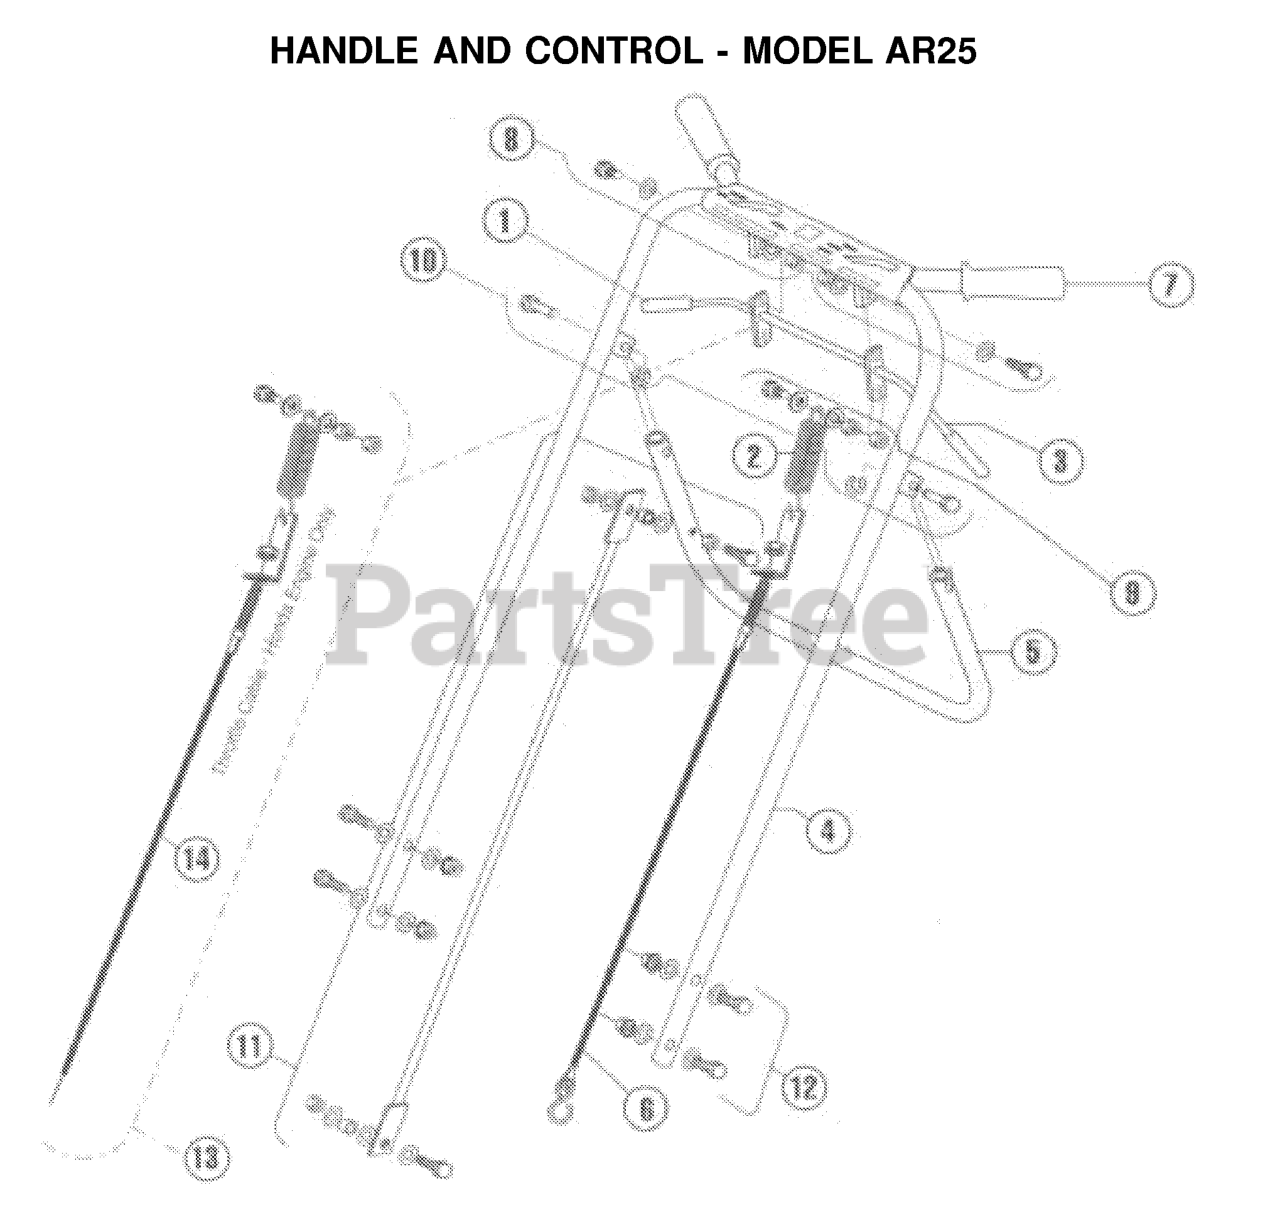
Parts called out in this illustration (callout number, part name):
1	GRIP, CLUTCH
2	SPRING
3	CLUTCH CONTROL KIT HUS
4	HANDLE WITH GRIPS
5	HANDLE, CONTROL, REAR WHEEL
6	CLUTCH CABLE
7	GRIPS, PAIR, 1" ID, BLACK
8	BOLT KIT CLUTCH CONTROL
9	CABLE KIT, CLUTCH
10	PIN KIT, REAR WHEEL
11	CONTROL ROD KIT HV
12	FASTENER KIT, HANDLE
13	THROTTLE CABLE KIT
14	THROTTLE CABLE
540007405	CLUTCH THROTTLE CONTROL HV
